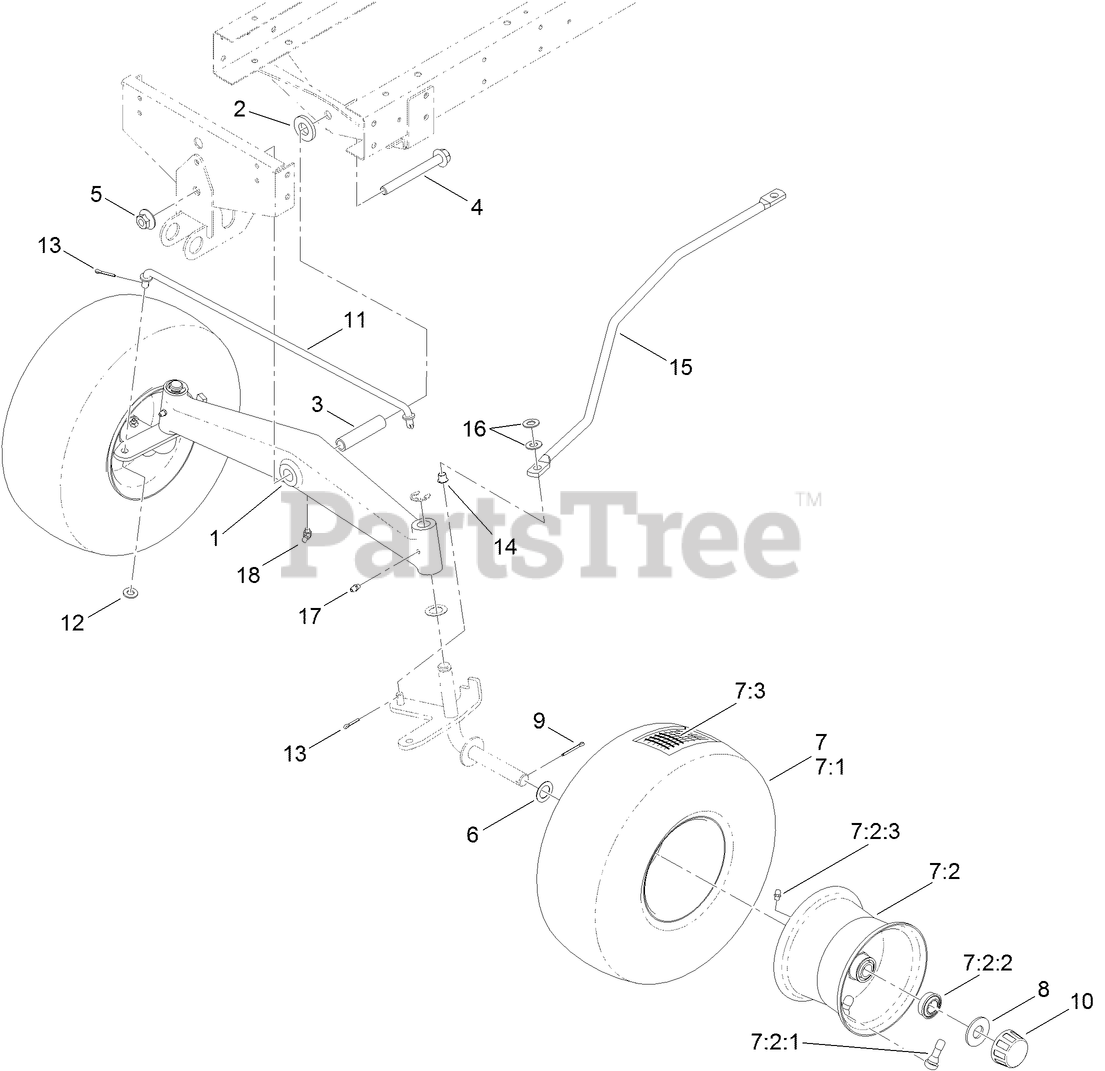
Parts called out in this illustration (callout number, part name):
1	Loose Parts Package
2	BUSHING-FRONT, AXLE
3	TUBE-FRONT, AXLE
4	SCREW-HHF
5	NUT-HF
6	WASHER-THRUST
7	WHEEL AND TIRE ASM
7:2:2	BEARING-WHEEL
7:2:3	FITTING-GREASE
7:3	TUBE-INNER
8	WASHER-PLAIN
9	PIN-COTTER
10	CAP-HUB
11	TIE ROD-STEERING
12	WASHER-FLAT
13	PIN-COTTER
14	BUSHING-FLANGED, NYLON
15	LINK-DRAG
16	WASHER-FLAT
17	FITTING-GREASE
18	FITTING-LUBE, 45 DEG
